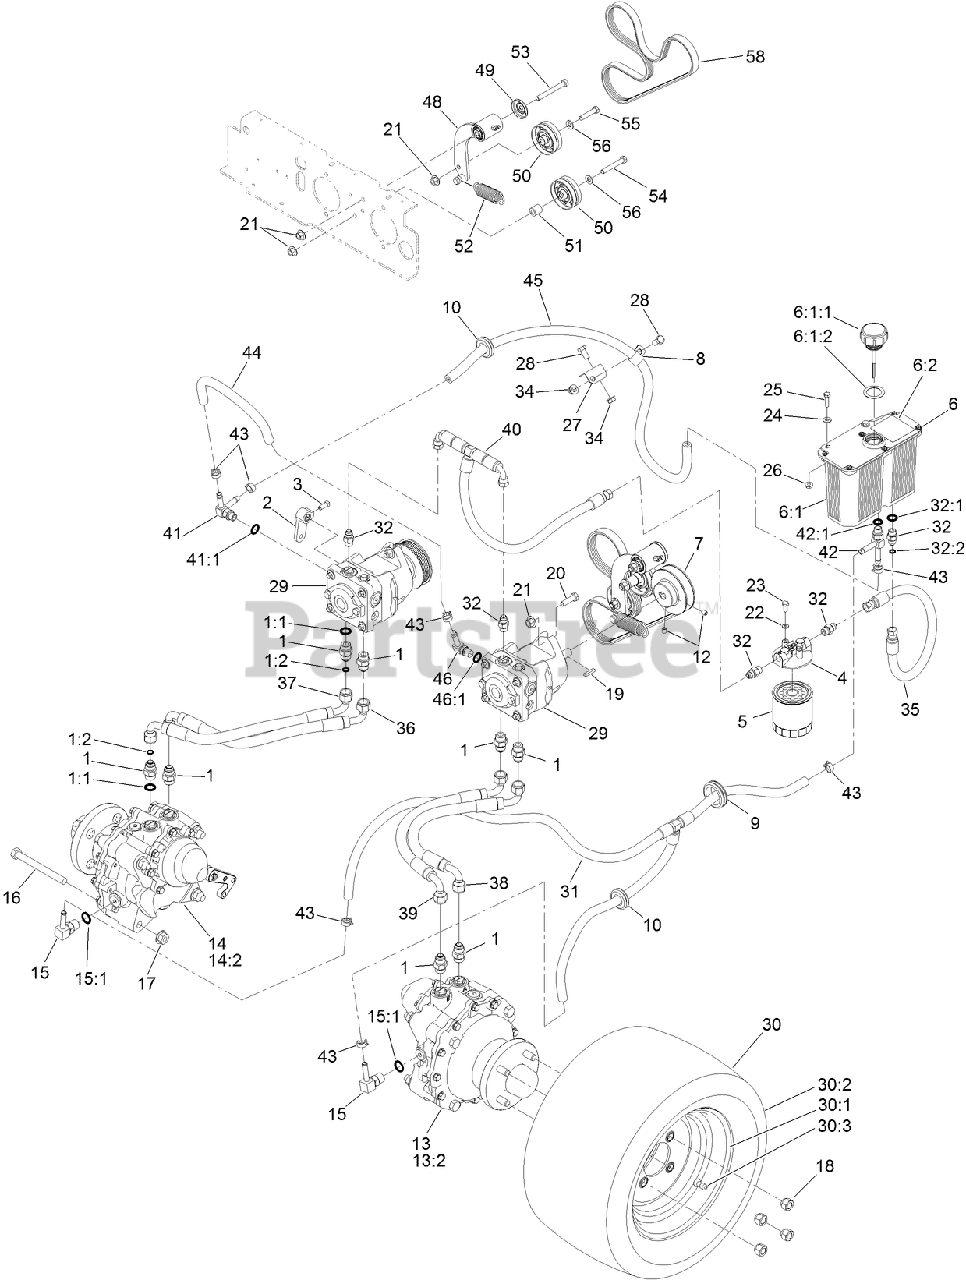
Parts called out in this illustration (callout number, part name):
1	FITTING-STRAIGHT
1:1	O-RING
1:2	O-Ring
2	ARM-CONTROL, PUMP
3	SCREW-SET, SQH
4	HEAD-FILTER
5	ELEMENT-FILTER, 25 MICRON
6	RESERVOIR ASM
6:1	Reservoir-HYD
6:1:1	RESERVOIR CAP ASM
6:1:2	GASKET-CAP
6:2	DECAL-WARNING
7	SHEAVE
8	CLIP-LOOM
9	Grommet
10	GROMMET
12	SCREW-SET
13	MOTOR-HYD, LH
13:2	SEAL KIT
14	MOTOR-HYD, RH
14:2	SEAL KIT
15	FITTING-HYD, 90 DEG
15:1	O-RING
16	SCREW-HH
17	NUT-HHF
18	NUT-LUG
20	SCREW-HH
21	NUT-FLANGE
22	WASHER-LOCK
23	SCREW-HH
24	WASHER-FLAT
25	SCREW-HH
26	NUT-HF
27	BRACKET-CLAMP
28	SCREW-HH
29	12CC HYDRO PUMP ASM
30	WHEEL AND TIRE ASM
30:3	STEM-VALVE
31	HYDRAULIC HOSE ASM
32	FITTING-STRAIGHT
32:1	O-Ring
32:2	O-RING
34	NUT-HHF, WHIZ
35	HYDRAULIC HOSE ASM
36	HYDRAULIC HOSE ASM
37	HYDRAULIC HOSE ASM
38	HYDRAULIC HOSE ASM
39	HYDRAULIC HOSE ASM
40	HYDRAULIC HOSE ASM
41	ADAPTER-TEE
41:1	O-RING
42	ADAPTER-RUN, TEE
42:1	O-RING
43	Clamp-Hose
44	HOSE-HYD
45	HOSE-HYD
46	FITTING-ELBOW, 90
46:1	O-RING
48	SHORT IDLER ASM
49	GUARD-TOP
50	PULLEY
51	Spacer-Mounting, Steering
52	SPRING-IDLER
53	SCREW-HH
54	SCREW-HH
55	SCREW-HH
56	WASHER-FLAT
58	BELT-V
